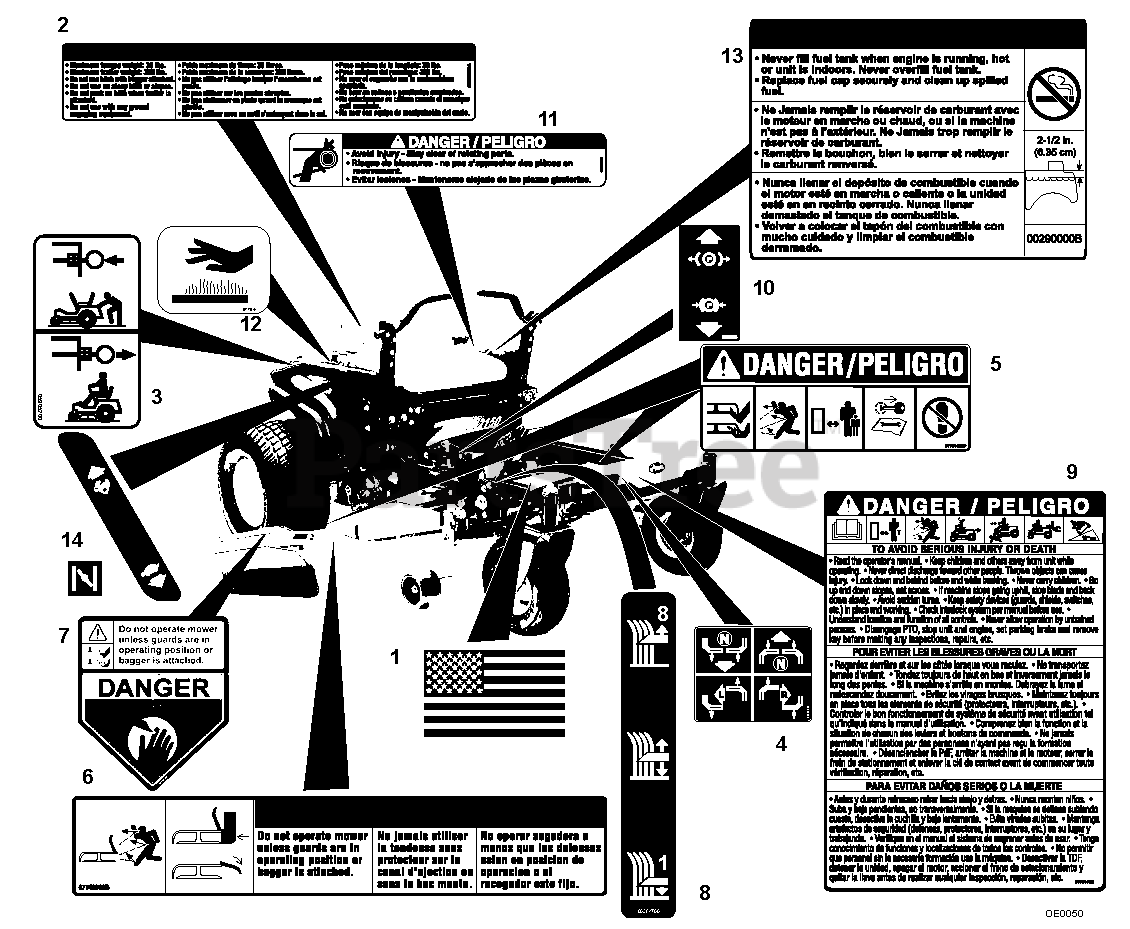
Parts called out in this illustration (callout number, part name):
1	Decal, American Flag
2	Decal, Trailer Hitch
3	Decal, Transmission Disconnect
4	Decal, Instructional Steering
5	Decal, Mower Pan Head Danger
6	Decal, Warning
7	Decal, CPSC Danger
8	Decal, Cut Height
9	Decal, Bilingual Danger
10	Decal, Parking Brake Lever
11	Decal, Danger
12	Decal, Hot Surface
13	Decal, Fuel Warning
14	Decal, Control
